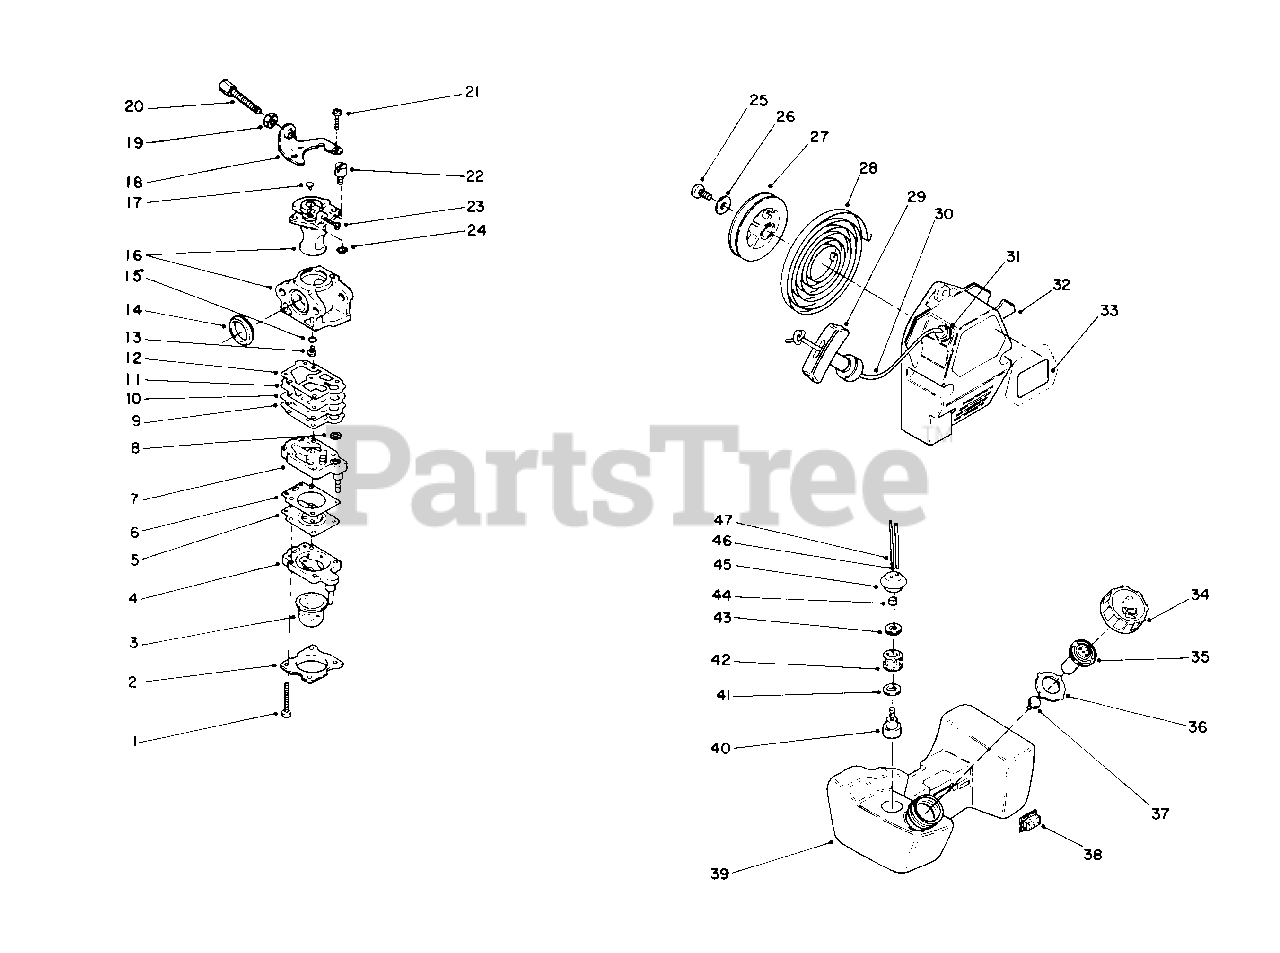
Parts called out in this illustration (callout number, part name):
2	Cover-Primer
3	Pump Assembly-Primer
4	Body-Primer
5	Diaphragm
6	Gasket-Diaphragm
7	Body-Pump
9	Gasket-Pump
11	Diaphragm
12	Gasket-Diaphragm
13	Jet-Main #43
14	Gasket-Rubber
15	O-Ring, Main Jet
16	Body-Carburator-(Ref.)
19	Nut-Lock
20	Screw-Adjustment
22	Holder-Wire
23	Valve-Throttle
29	Knob-Starter
30	Rope-Starter
32	Case-Starter
33	Decal-Toro
34	Cap-Fuel
35	Valve-Breather
37	Cap-Valve
39	Tank Assembly-Fuel (Incl. Ref. #34-47)
40	Weight-Filter
41	Seal-Dust
42	Filter-Seal
43	Washer-Seal
45	Grommet-Fuel Tank
46	Hose-Fuel
47	Tube-Fuel Return
